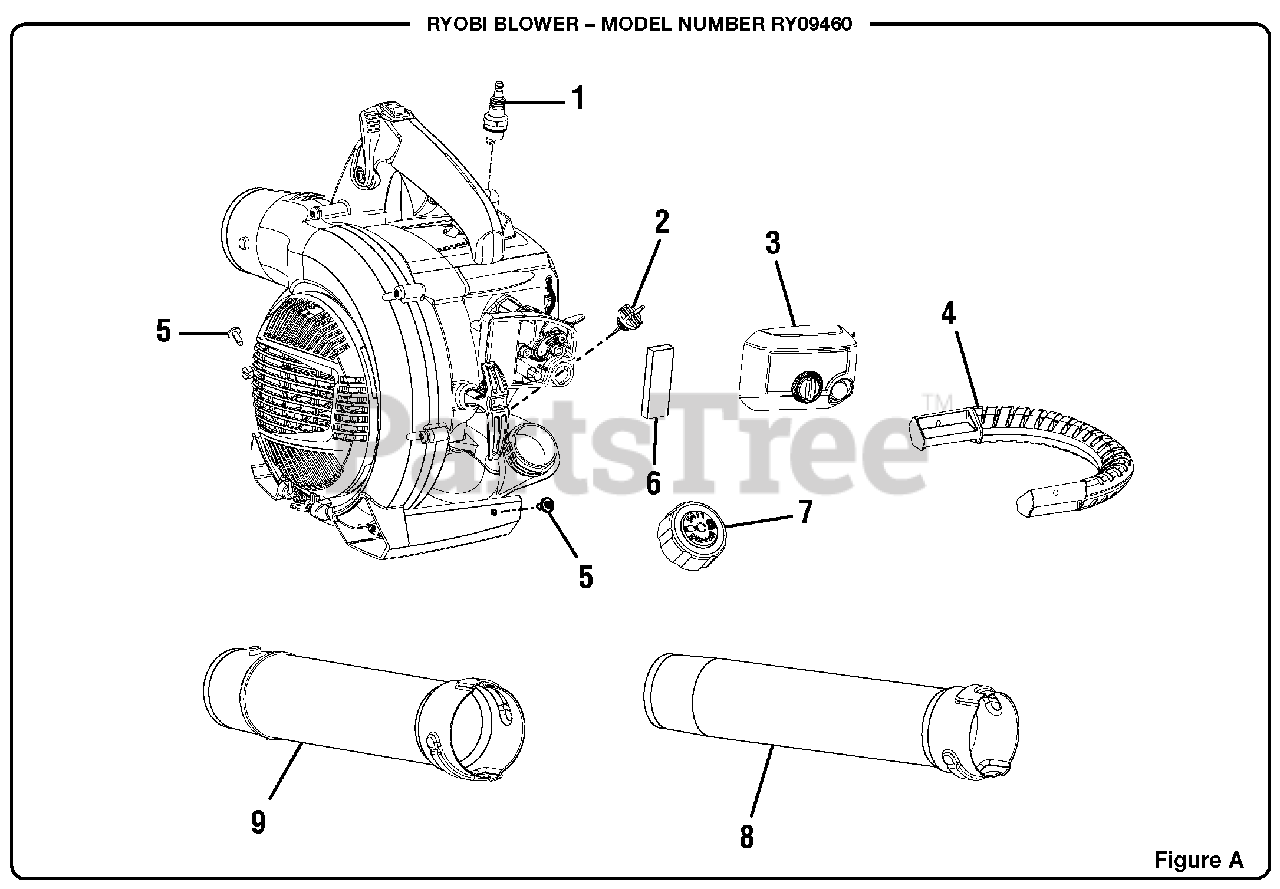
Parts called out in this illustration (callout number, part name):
1	Spark Plug (RY4C)
2	Oil Fill Cap w/Dipstick
3	Air Filter Cover
5	Screw (10-14 x 1/2 in.)
7	Fuel Cap Assembly
8	Sweeper Nozzle
9	Upper Blower Tube
